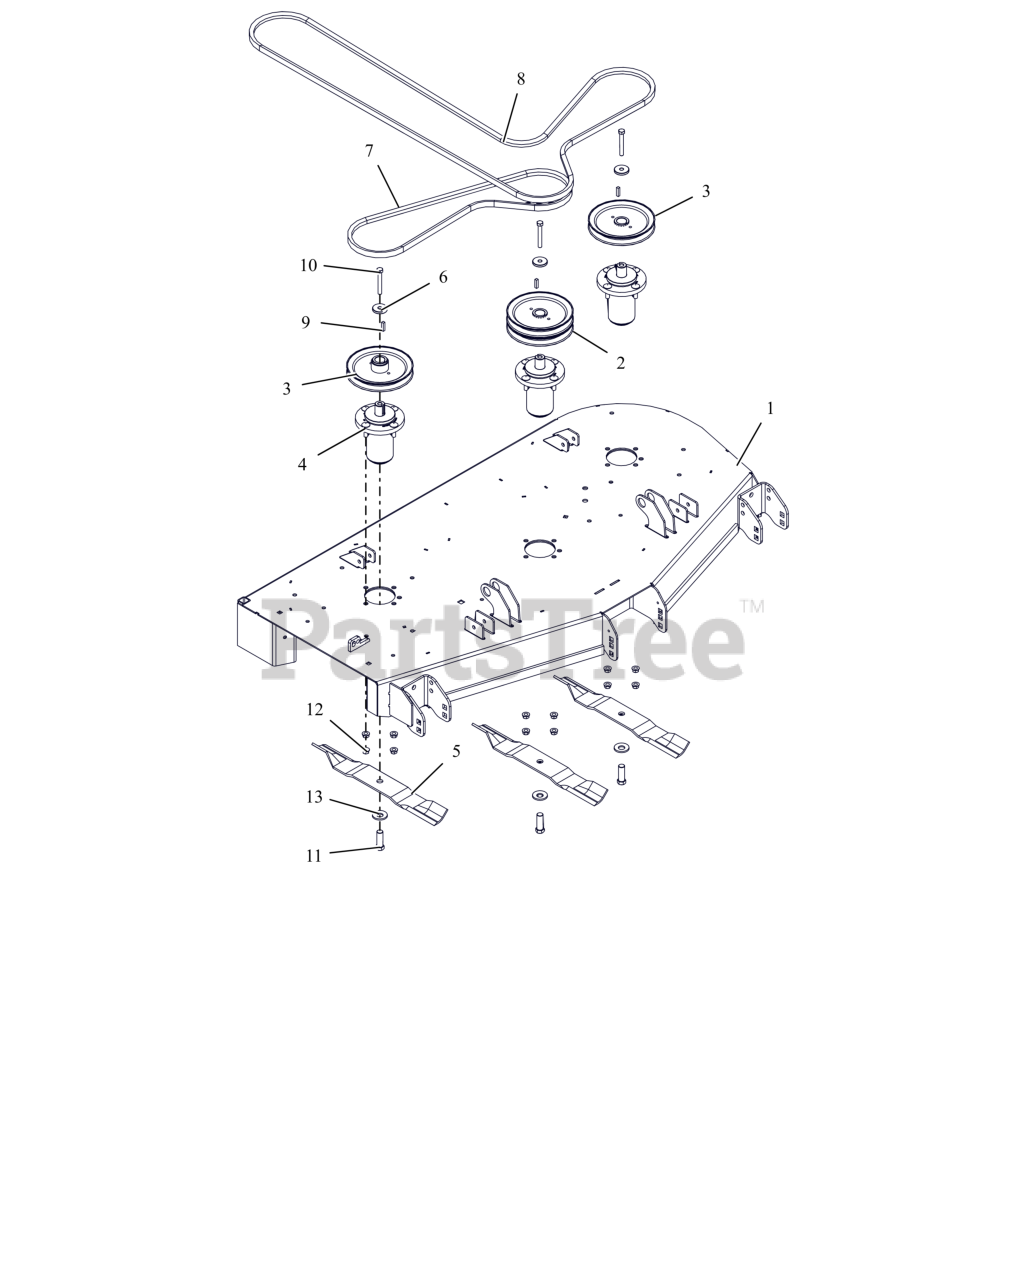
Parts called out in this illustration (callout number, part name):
1	KIT,DECK-52" W/DECALS-GRAVELY
2	PULLEY, DOUBLE-1"ID X 6.75"OD
3	PULLEY, V-1" ID X 6.75" OD
4	ASM, MAINT FREE ALUM SPINDLE
5	BLADE, 18"
6	RETAINER, SHEAVE
7	V-BELT, B-COGGED
8	V-BELT, HB SECTION
9	KEY, SQ .25X.25X1.00 RC 40-50
10	BLT, HEX .38-16X2.75 G8 ZCC
11	BLT, HEX .62-18X1.75 G8 ZCC
12	NUT-LK-CTR-FLG .375-16 GF ZCC
13	WSHR-BLVL .669X1.535X.138
